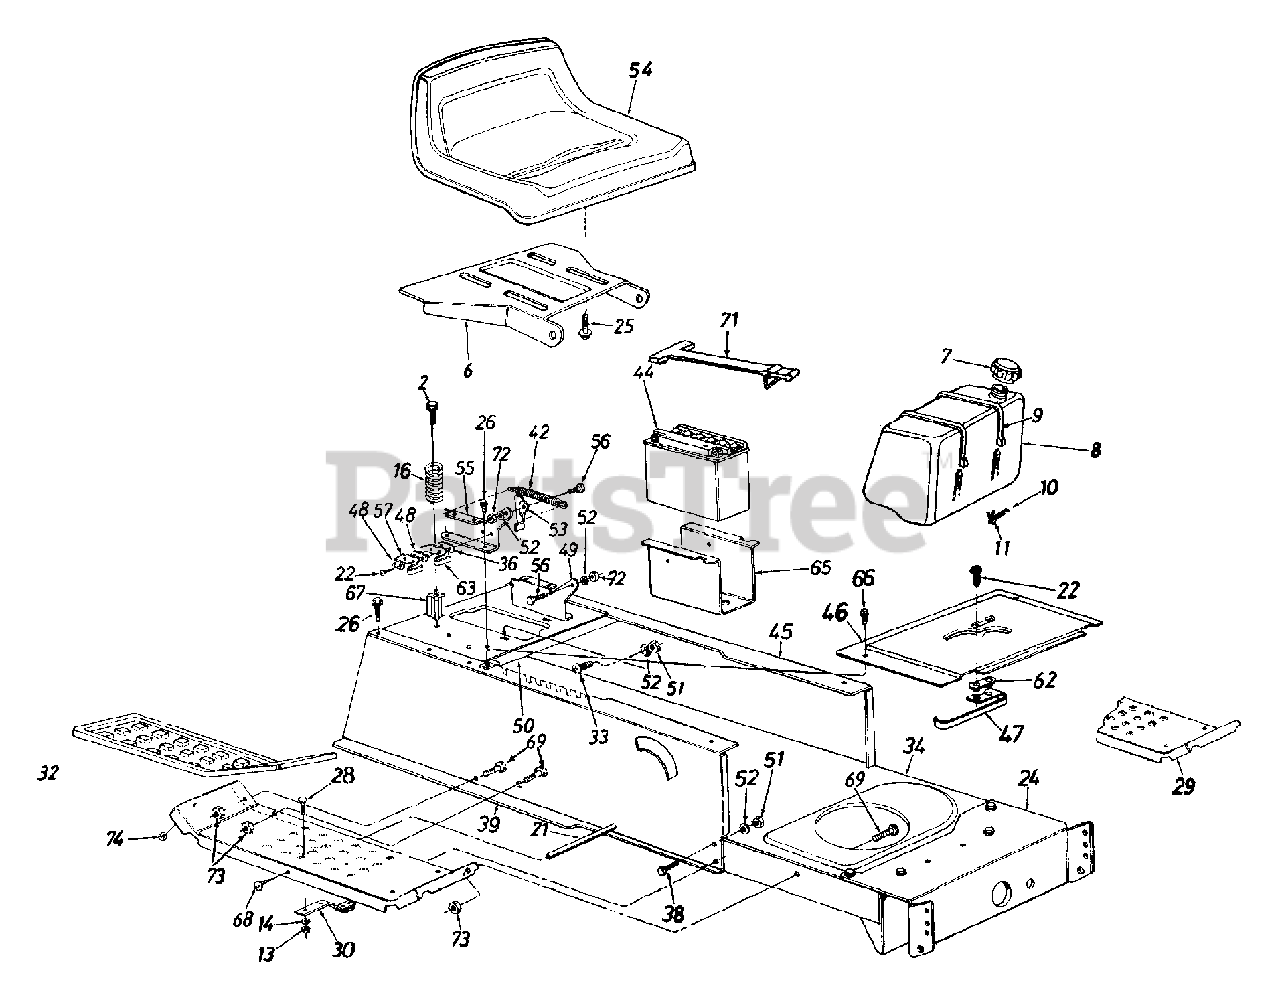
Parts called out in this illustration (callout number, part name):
2	Hex Tap Scr. 5/16-18 x 3.25"
7	Fuel Cap
8	Fuel Tank (1.5 Gal)
9	Tie Strap
10	Fuel Line
13	Hex Nut 1/4-20 Thd.
14	L-Wash. 1/4" I.D.
16	Compression Spring
21	Running Board Rod
22	Hex AB-Tap Scr. #8 x .50" Lg.
25	Hex Tap Scr. 3/8-16 x .62" Lg.
26	Hex Wash. Hd. AB-Tap Scr. 5/16 x .75"
28	Carriage Bolt 1/4-20 x .62
32	Rubber Foot Pad - L.H.
36	Insulator Boss Plate
38	Hex Bolt 5/16-18 x .75" Lg.
44	12-V Battery
47	Reverse Safety Switch
48	Insulator Plate
52	L-Wash. 5/16" I.D.
53	Seat Lift Brkt.
54	Seat - Grey
56	Shld. Bolt .437" Dia. x .268"
57	Spring Switch (Seat - Outer)
62	Insulatop Nut Plate
63	Safety Switch (Seat - Inner)
66	Truss Mach. B-Tap Scr. #10 x .5" Lg.
67	Spring Spacer
68	Truss Mach. Scr. 5/16-18 x .75"
69	Hex Bolt 5/16-18 x .75" Lg.
71	Battery Retainer Strap
72	Hex Nut 5/16-18 Thd.
73	Hex Sems Nut 5/16-18 Thd.
74	Hex Sems Nut 1/4-20 Thd.
